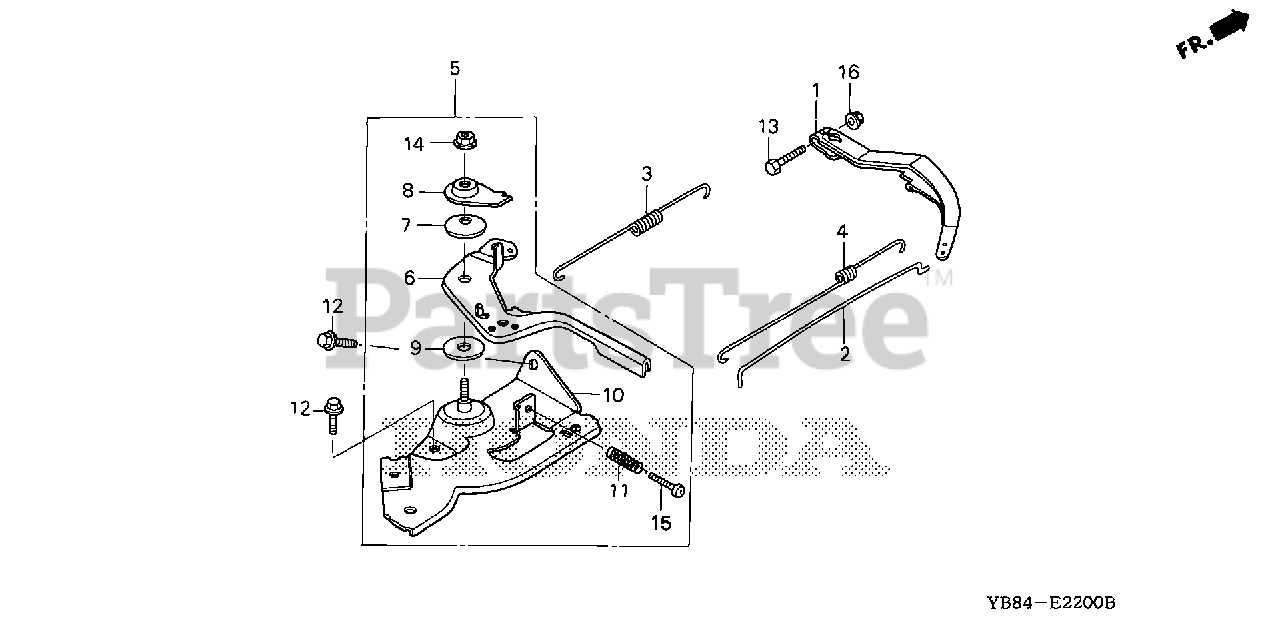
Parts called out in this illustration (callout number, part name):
1	ARM, GOVERNOR
2	ROD, GOVERNOR
3	SPRING, GOVERNOR
4	SPRING, THROTTLE RETURN
5	CONTROL ASSY.
6	LEVER, CONTROL
7	SPRING, LEVER
8	WASHER, CONTROL LEVER
9	SPACER, CONTROL LEVER
10	BASE, CONTROL
11	SPRING, CONTROL ADJUSTING
12	BOLT, FLANGE (6X12) (CT200)
13	BOLT, GOVERNOR ARM
14	NUT, SELF-LOCK (6MM)
15	SCREW, PAN (5X25)
16	NUT, FLANGE (6MM)
